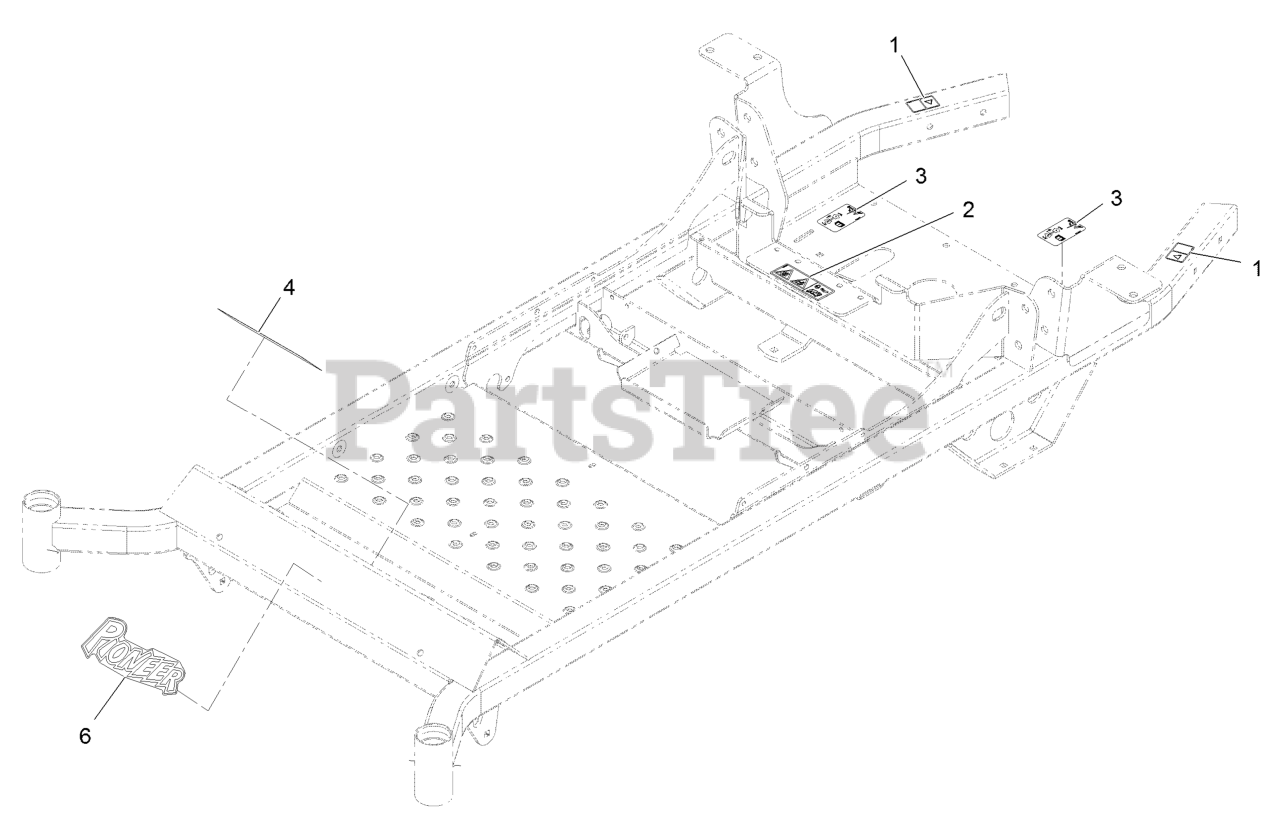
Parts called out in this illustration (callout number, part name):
1	DECAL-WARNING
2	DECAL-WARNING
3	DECAL-RELEASE, DRIVE
4	DECAL-WARNING, SLOPE
6	DECAL-PIONEER LOGO
